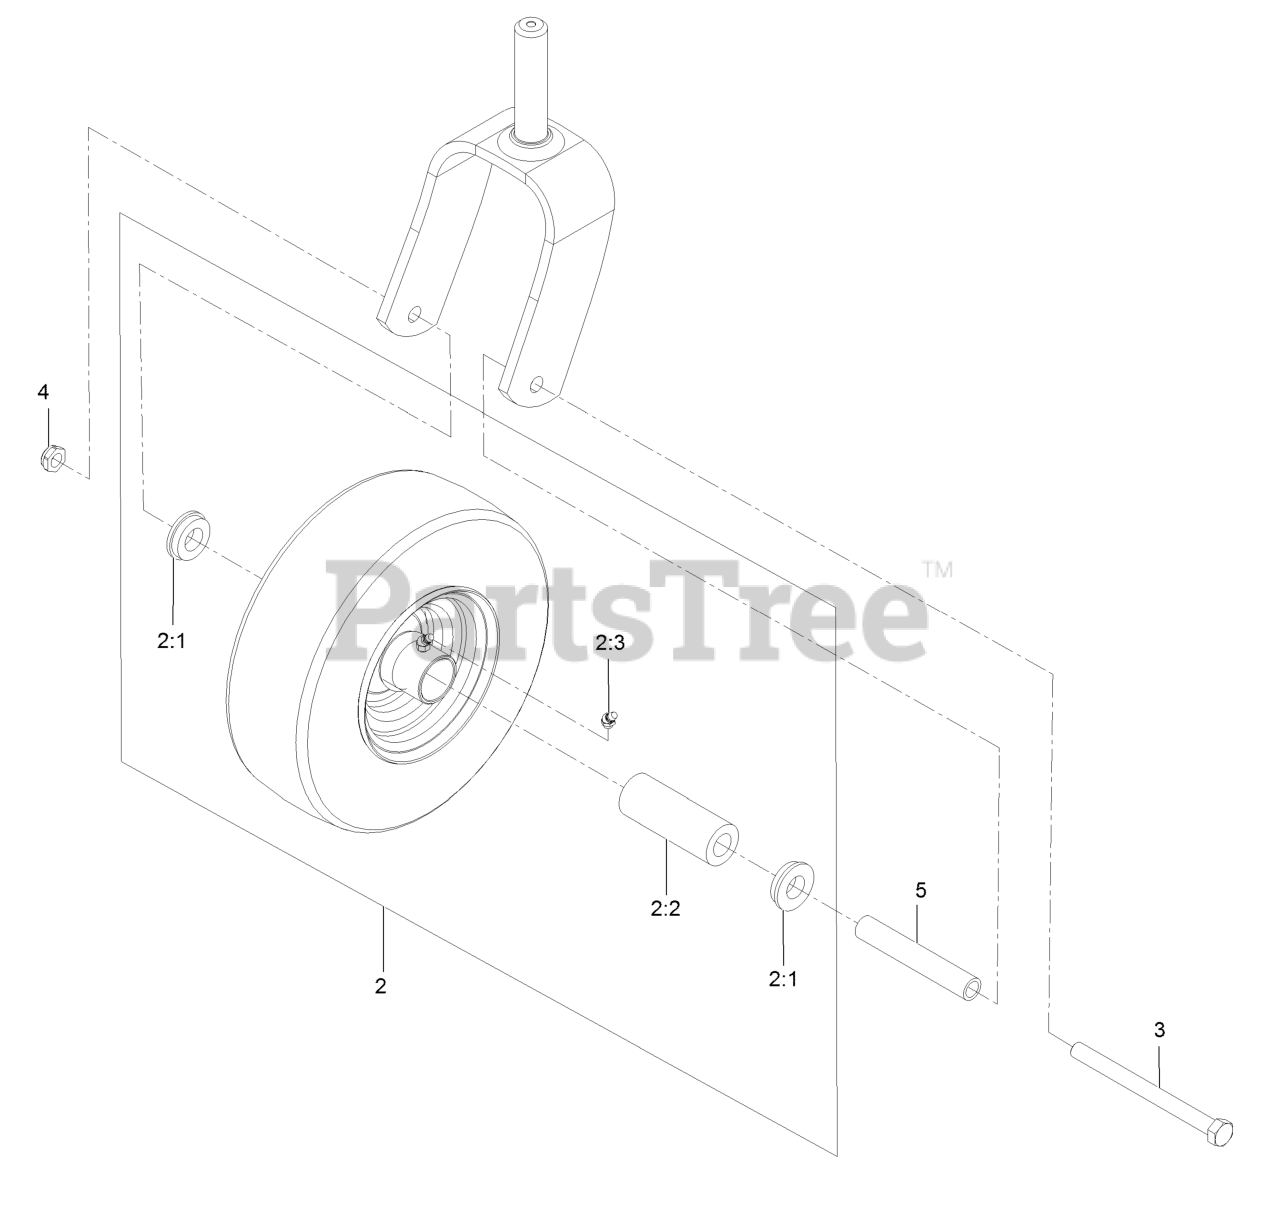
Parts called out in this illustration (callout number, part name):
2	Wheel And Tire ASM
2:1	Bushing-Flanged
2:2	Bearing
2:3	Zerk-45deg 1/4-28
3	Screw-HH 1/2-13 X 6
4	Nut-Nyloc 1/2-13 Thin
